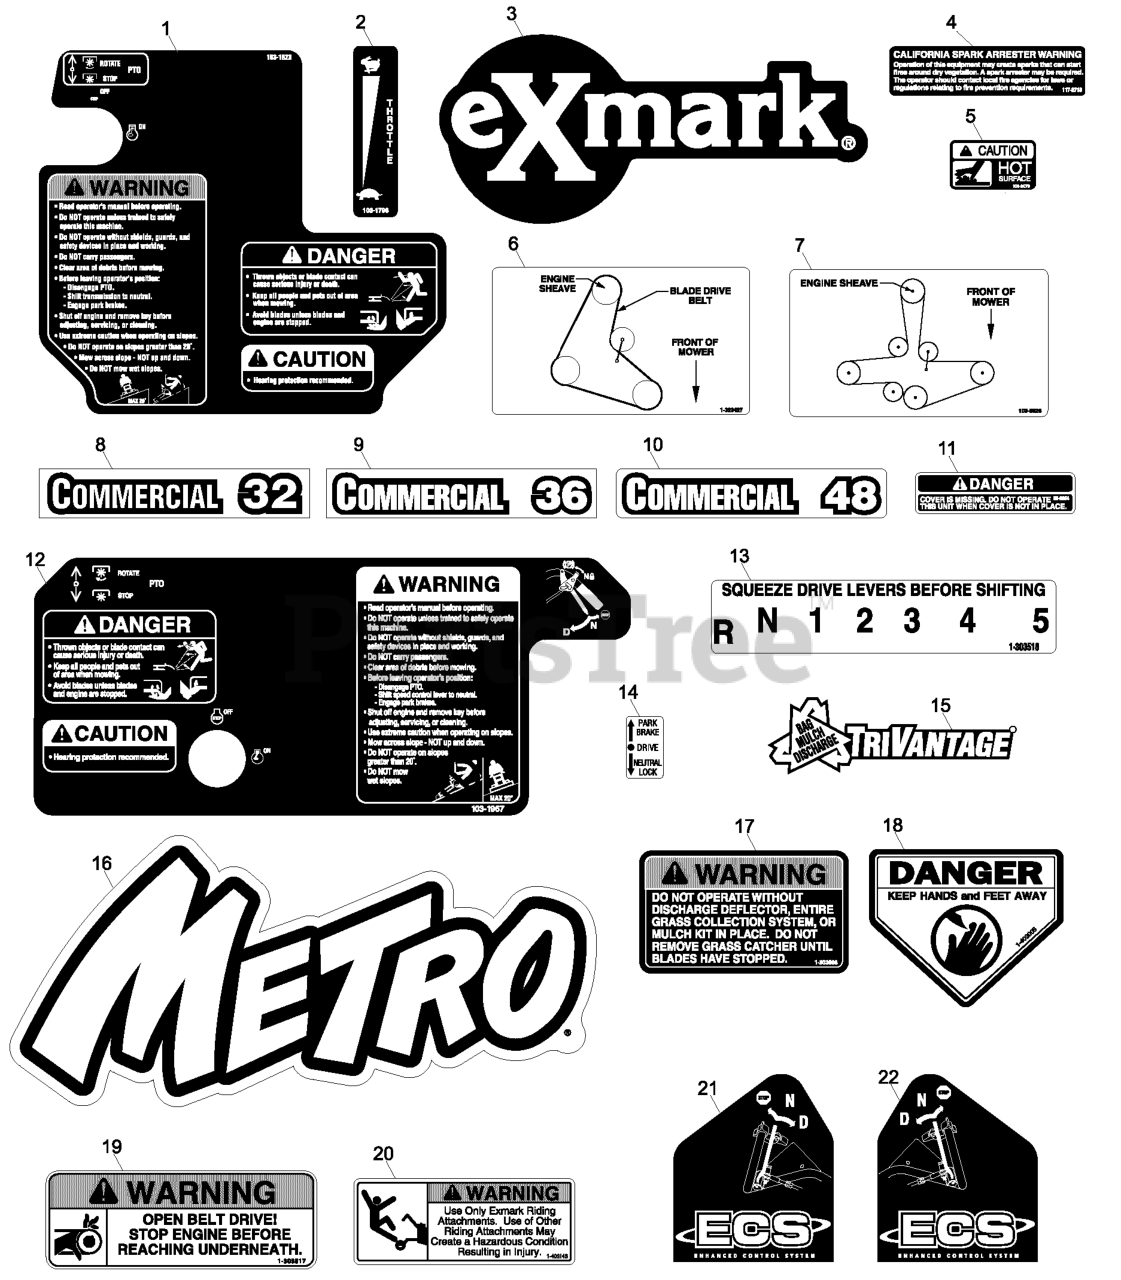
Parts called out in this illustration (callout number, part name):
1	DECAL,METRO ECS CONSOLE
2	DECAL,THROTTLE ONLY
3	DECAL,EXMARK LOGO
4	DECAL-ARRESTER, SPARK
5	DECAL-CAUTION
6	DECAL,BELT ROUTING 32/36
7	DECAL,BELT ROUTING
8	DECAL,COMMERCIAL 32
9	DECAL,COMMERCIAL 36
10	DECAL,COMMERCIAL 48
11	DECAL-COVER, MISSING
12	DECAL,CONSOLE
13	DECAL,SHIFTER
14	DECAL,NEUTRAL/BRAKE
16	DECAL,METRO MODEL
17	DECAL-WARNING, DISCHARGE
18	DECAL-DANGER
19	DECAL,BELT DRIVE
20	DECAL,SULKY WARNING
21	DECAL,RH ECS INSTRUCTION
22	DECAL,LH ECS INSTRUCTION
